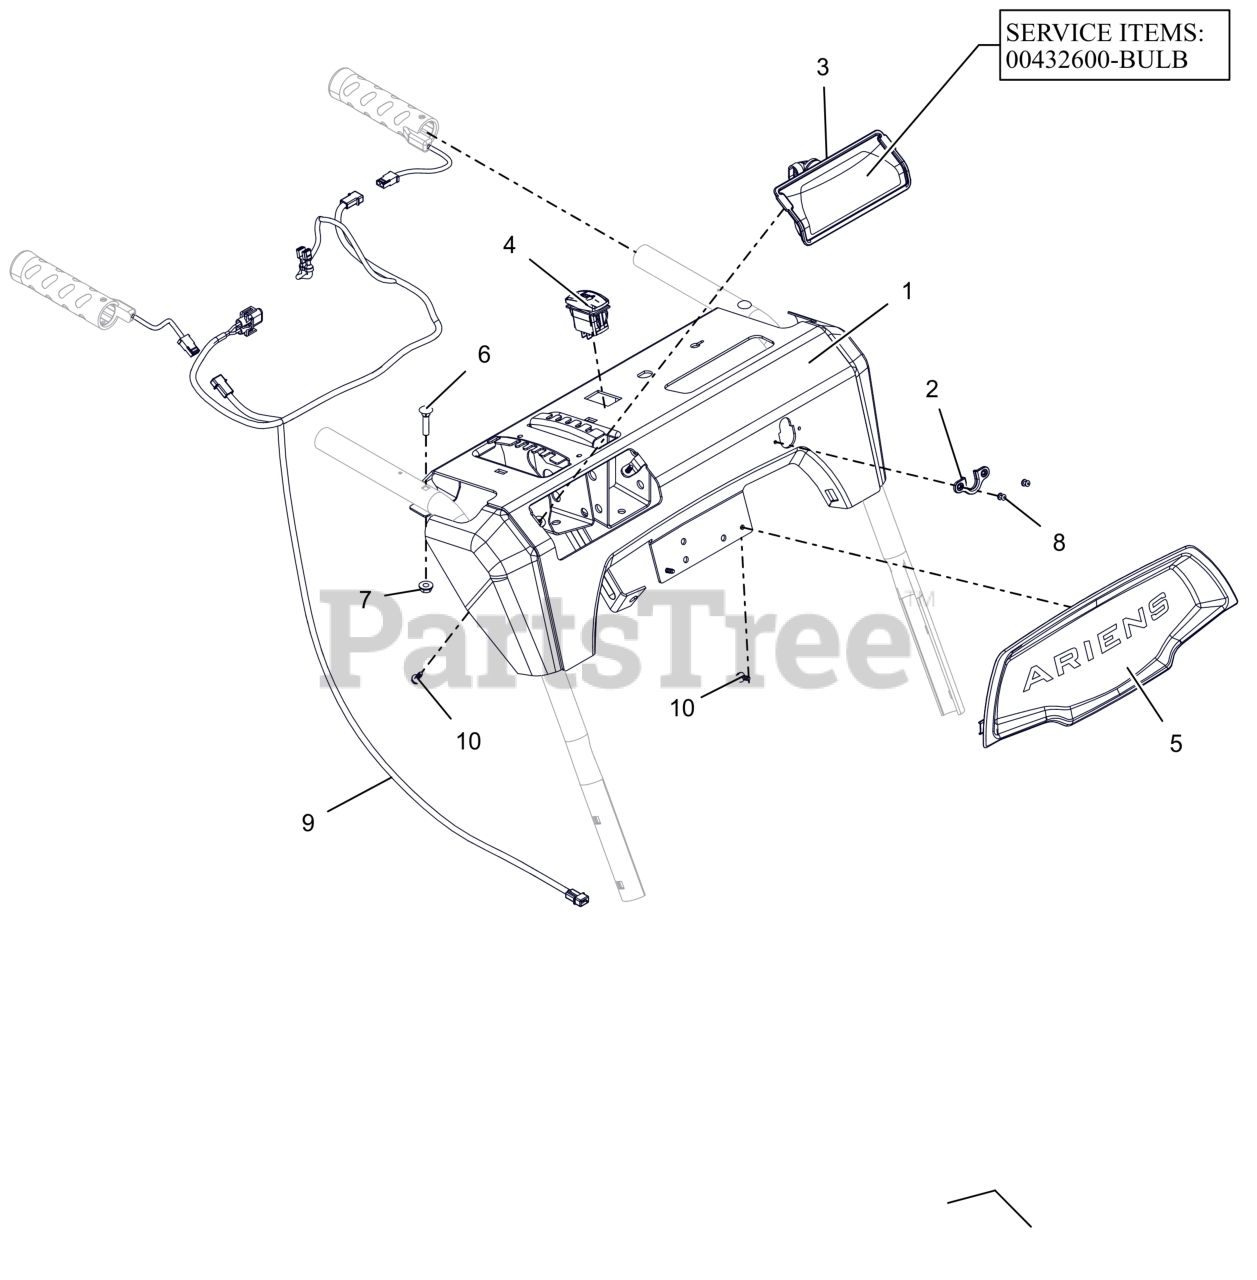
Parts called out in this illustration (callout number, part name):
1	CONTROL PANEL W/DECAL FRIC-QT
2	GROMMET, CABLE, QUICK TURN 2
3	HEADLIGHT ASY, HALO 20W 2SHOT
3	BULB, LIGHT-HALOGEN 20W
4	SWITCH,ROCKER SPST-ON/OFF
5	BEZEL, DASH - ARIENS LG DASH
6	BLT-RDHDXLSQNK.25-20X1.25 G5ZC
7	NUT-LK-CTR-FLG .25-20 ZC120
8	RVT-POP #43 .125X.313 STL ZINC
9	HARNESS, LIGHT & WARMER
10	SCR, PLASTIC #10X.50
